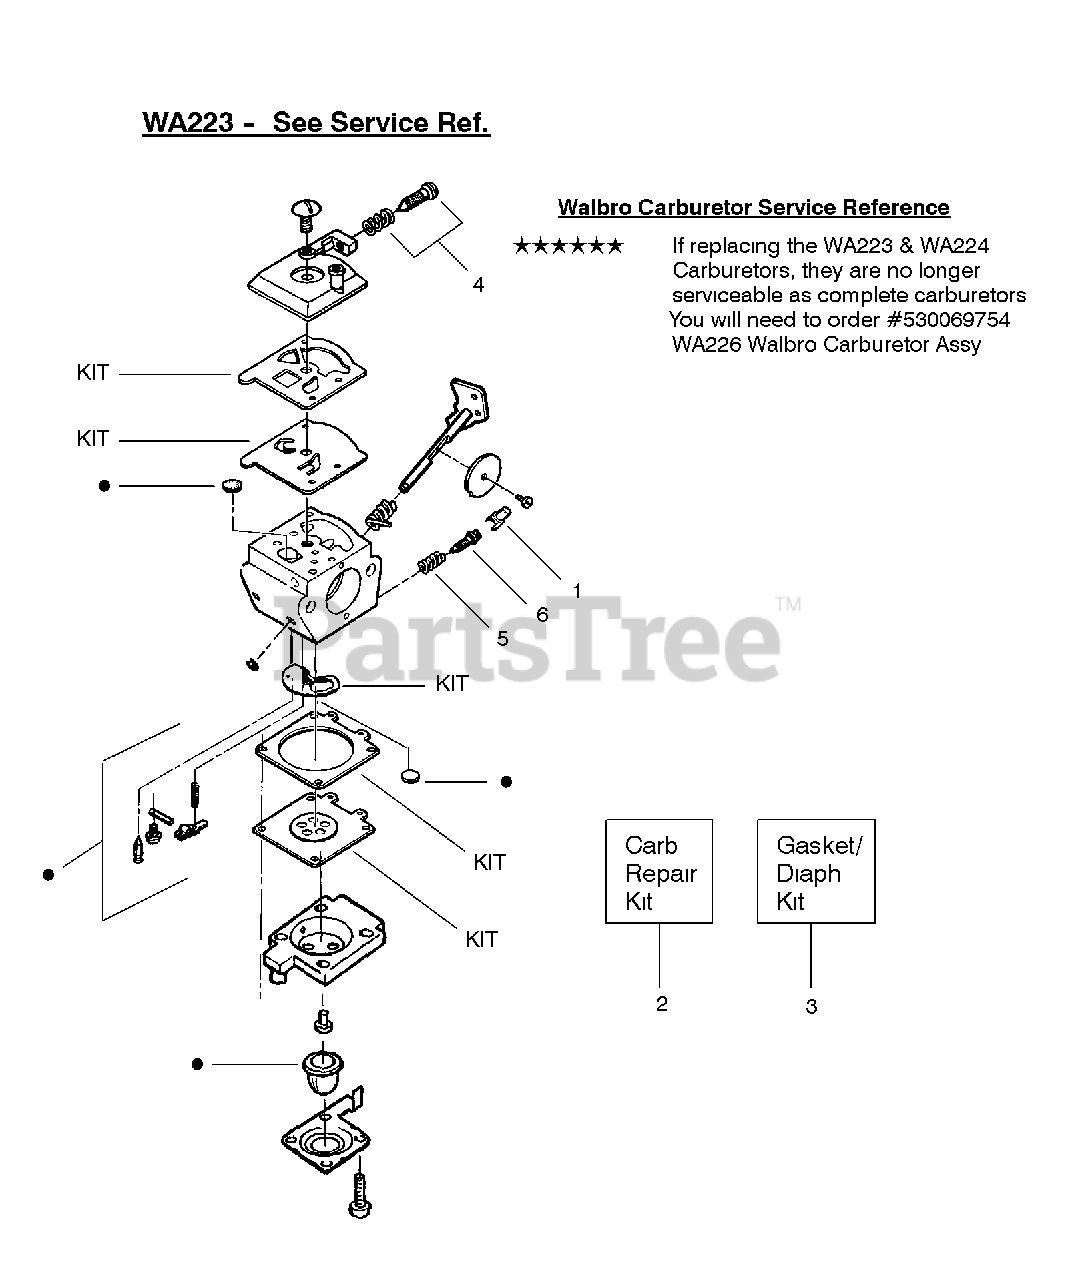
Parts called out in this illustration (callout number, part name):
1	Limiter Cap
2	Carburetor Repair Kit WA223
3	Gasket/Diaphragm WA223, WA224 & WA226
4	Idle Screw & Spring Kit
5	Low Speed Spring
6	Low Speed Needle
